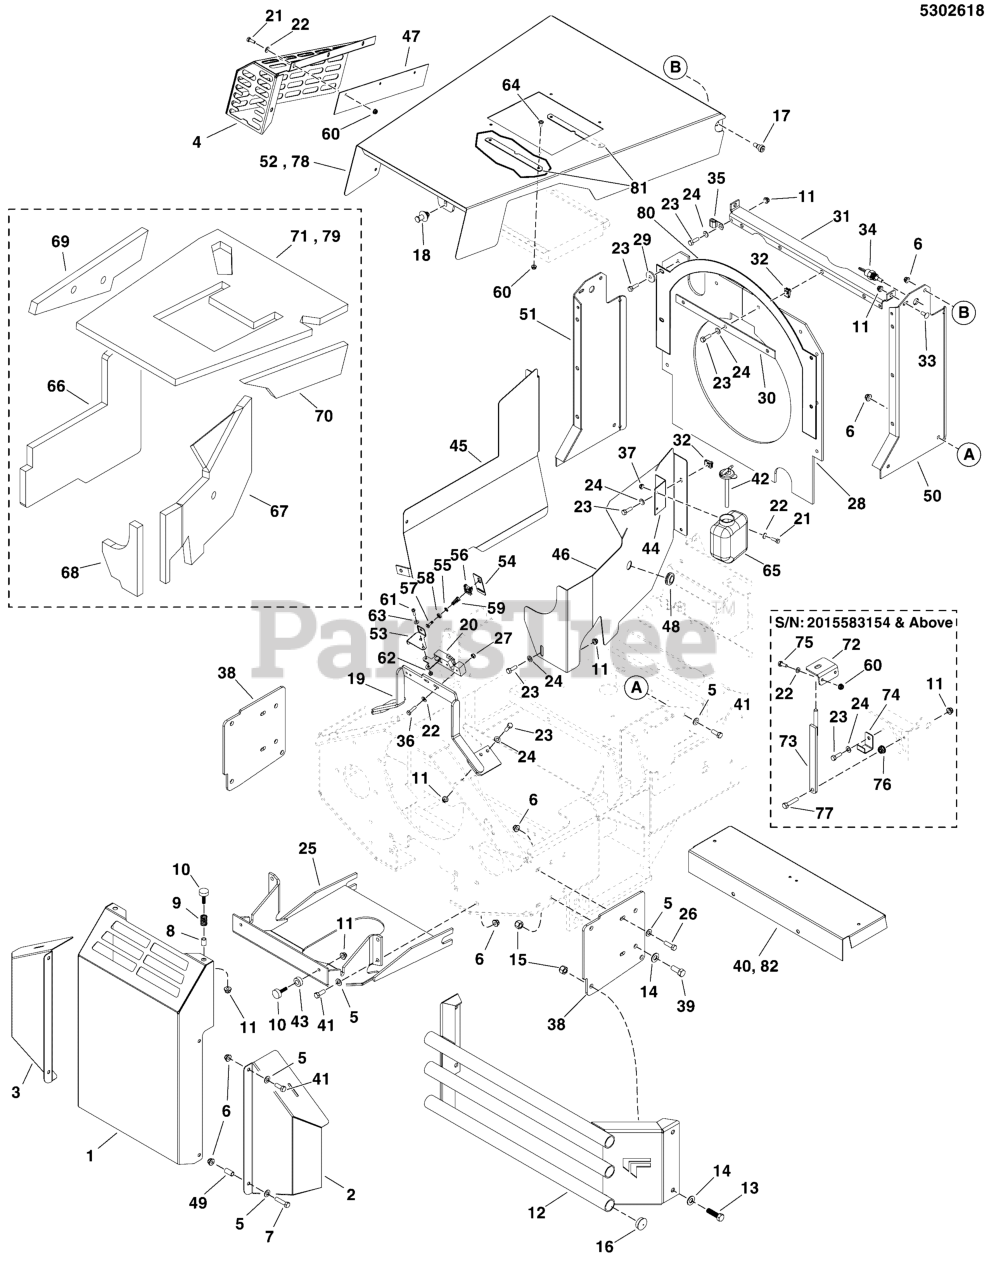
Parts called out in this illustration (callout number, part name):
1	WELD, CENTER BUMPER IS5000 - RED
2	WELD, BUMPER SIDE RH IS5000 - RED
3	WELD, BUMPER SIDE LH IS5000 - RED
4	WELD, MUFFLER GUARD, IS5100ZCE
5	WASHER, 3/8 SAE
6	NUT, 3/8-16 HEX NYLOCK FLANGE
7	BOLT, 3/8-16 X 1-3/4" GD5 CZ
8	SPACER, .38 X .50 X .75
9	SPRING, HOOD LATCH
10	BUMPER, RUBBER, 5/16-18
11	NUT, 5/16-18 HEX NYLOCK FLANGE
12	WELD, BUMPER, SERVICE IS4500 - RED
13	BOLT, 1/2-20 X 1-3/4" GD8 CZ
14	WASHER, 1/2 SAE
15	NUT, Hex, Nylon Lock, 1/2-20
16	PLUG, PANEL, 1.25 - BLACK
17	BOLT, 3/8-16 X 3/8, 1/2 SHOULDER
18	BOLT/WASHER ASM HOOD LATCH
19	WELD, MOUNT HOOD LATCH - RED
20	HOOD LATCH, IS5000
21	BOLT, 1/4-20 X 3/4 GD5 YZ
22	WASHER, 1/4 SAE
23	BOLT, 5/16-18 X 1 GD5 YZ
24	WASHER, 5/16" SAE
25	WELD, SKID PLATE - RED
26	BOLT, 3/8-16 X 1-1/4" GD5 CZ
27	NUT, 1/4-20 HEX NYLON LOCK
28	SHROUD, RUBBER, IS5100Z
29	WASHER, .34 X 1.25 X 10 GA
30	BAR, RUBBER SUPPORT SIDE
31	SHROUD, SUPPORT
32	BODY CLIP, 5/16-18-7GA MATERIAL
33	BOLT, 5/16-18 X 3/4, CARRIAGE
34	PIN, LATCH, SPR LOADED-PULL ACT
35	CLAMP, 5/16, DOUBLE, WIRE & TUBE
36	BOLT, 1/4-20 X 1" GD5 CZ
37	NUT, 1/4-20 HEX SERR. FLANGE
38	PLATE, BUMPER MOUNT - RED
39	BOLT, 1/2-20 X 1-1/4" GD5 CZ
40	SHIELD, DEBRIS - RED
41	BOLT, 3/8-16 X 1" GD5 CZ
42	CAP, EXPANSION TANK
43	SPACER, .52 X 1.00 X .38, CZ
44	BRACKET, COOLANT RESERVOIR - RED
45	WELD, SOUND BAFFLE, LH - RED
46	PLATE, SOUND SHIELD, RH - RED
47	PLATE, HOOD, SOUND SHIELD - RED
48	GROMMET, 3/4
49	SPACER, .38 X .50 X 1.00
50	WELD, SHROUD CHANNEL - RH - RED
51	WELD, SHROUD CHANNEL - LH - RED
52	WELD, HOOD, IS5100ZCE - RED
53	PLATE HOOD LOCKING LATCH, CE - RED
54	PLATE CLIP LOCK, CE - RED
55	DZUS, RETAINER, PUSH-ON, SS
56	DZUS, RECEPTACLE, CLIP-ON, D8
57	DZUS, 1/4 TURN FASTENER, D8X16MM
58	DZUS, CUPPED WASHER
59	DZUS, EJECTOR SPRING
60	NUT, 1/4-20 HEX NYLOCK FLANGE
61	SCREW, #10-24 X 3/4 ROUND PHILLIPS
62	NUT, #10-24 HEX NYLON LOCK
63	WASHER, #10 SAE
65	EXPANSION TANK, COMPLETE
66	FOAM, SOUND BAFFLE, LH
67	FOAM, SOUND SHIELD, RH
68	FOAM, SOUND SHIELD
69	FOAM, HOOD, SOUND SHIELD, LH
70	FOAM, HOOD, SOUND SHIELD, RH
71	FOAM, HOOD, SOUND SHIELD
72	BRACKET, HOOD PROP, POCKET
73	WELD, HOOD PROP, IS5100
74	BRACKET, HOOD PROP, RETAINER
75	BOLT, 1/4-20 X 3/4 GD5
76	NUT, 5/16-18 HEX SERRATED FLANGE (LARGE)
77	BOLT, 5/16-18 X 1-1/2 GD5 YZ
78	WELD, HOOD, IS5100Z - RED
79	FOAM, HOOD, SOUND SHIELD
80	PLATE, RUBBER SHROUD RETAINER - RED
81	BAR, SUPPORT, AIR COOLER, IS5100Z - BLK
82	SHIELD, DEBRIS - RED
